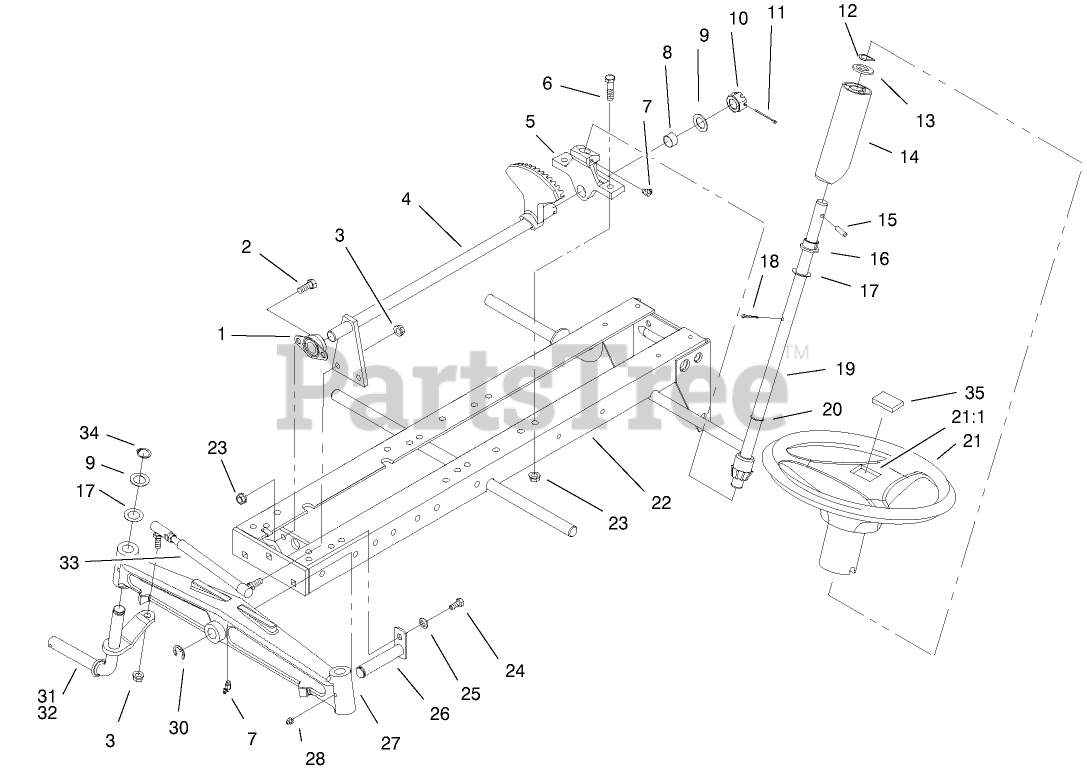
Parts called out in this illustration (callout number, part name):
1	BEARING-FLANGED
2	SCREW-HH
3	NUT-LOCK
4	LOWER STEERING ASM
5	SUPPORT-LOWER, STEERING
6	SCREW-HH
7	FITTING-LUBE, 45 DEG
8	BEARING-BRONZE
9	WASHER
10	NUT-HEX, SLOTTED
11	PIN-COTTER
12	WASHER-BOWED
13	WASHER-FLAT
14	TUBE-STEERING
15	PIN-ROLL
16	BEARING-FLANGED
17	WASHER-SHIM
18	PIN-COTTER
19	STEERING SHAFT ASM
20	O-RING
21	WHEEL-STEERING
21:1	COVER-WHEEL, STEERING
22	FRAME ASM
23	NUT-LOCK, NI
24	SCREW-HH
25	WASHER-LOCK
26	PIN AND PLATE ASM
27	AXLE-FRONT
28	FITTING-GREASE
30	E-RING
31	SPINDLE ASM
31	SPINDLE ASM-RH
32	SPINDLE ASM-LH
32	SPINDLE ASM-RH
34	RING-RETAINING
35	DECAL
